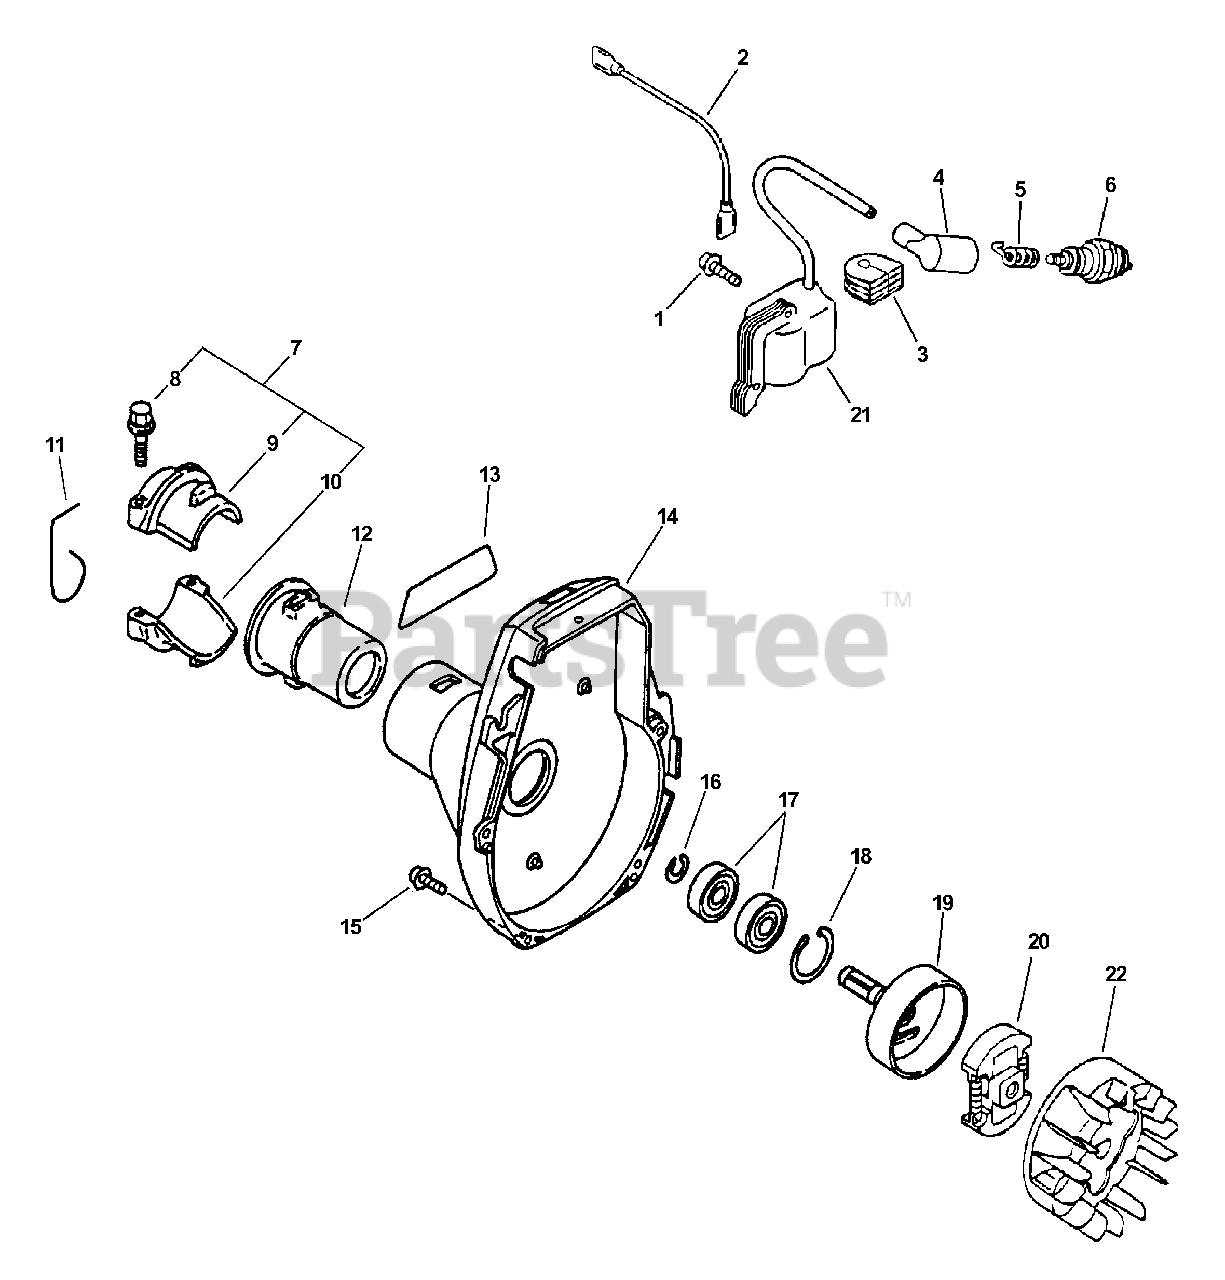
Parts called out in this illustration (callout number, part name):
1	SCREW - 4X22
2	LEAD - IGNITION
4	CAP, SPARK PLUG
5	TERMINAL, SPARK PLUG CAP
6	SPARK PLUG -- BPM-7Y
6	SPARK PLUG -- BPMR-7A
7	MAIN PIPE CLAMP KIT
8	BOLT - 5X25
9	CLAMP, MAIN PIPE - UPPER
10	CLAMP, MAIN PIPE - LOWER
11	CLIP
13	LABEL - MODEL SRM-2400
14	LABEL - MODEL SRM-2410
14	CASE, FAN
15	SCREW - 4X16
16	RING, RETAINING - 12
17	BEARING, BALL - 6001
18	RING, RETAINING - 28
19	DRUM, CLUTCH
20	CLUTCH ASSY
21	COIL, IGNITION
22	FLYWHEEL
